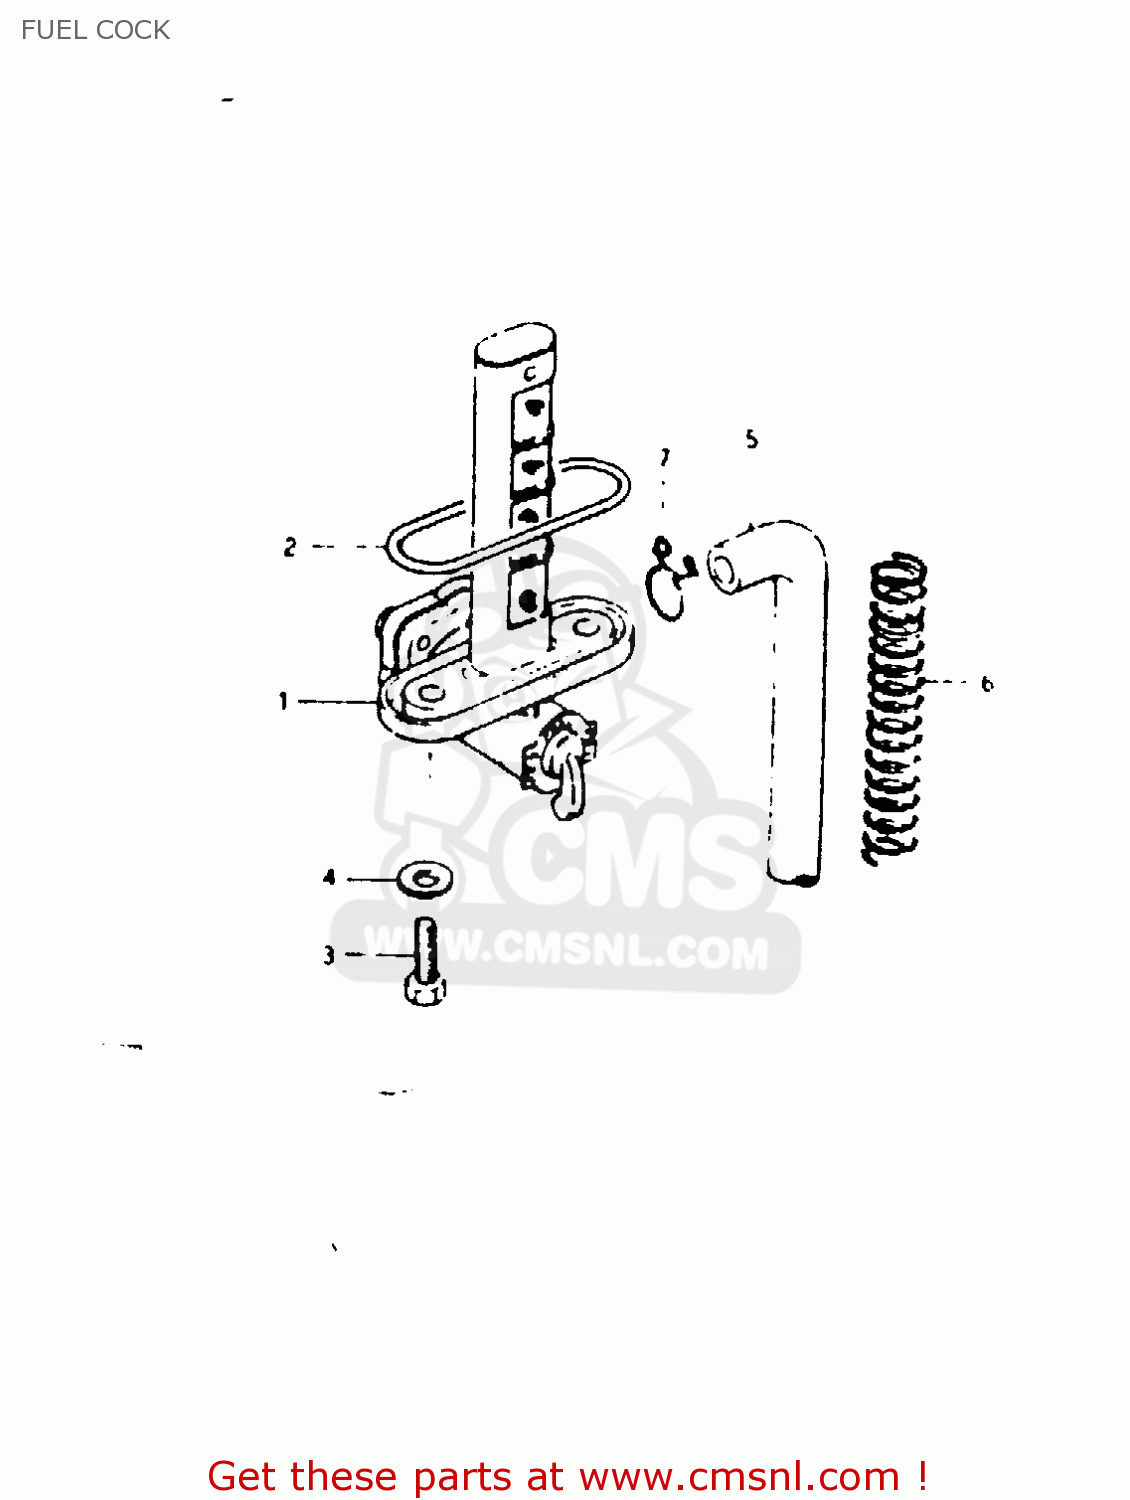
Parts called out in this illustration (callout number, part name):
1	COCK ASSEMBLY,FUEL
2	O RING
3	BOLT(6X20)
4	GASKET
5	HOSE
6	SPRING
7	CLIP
